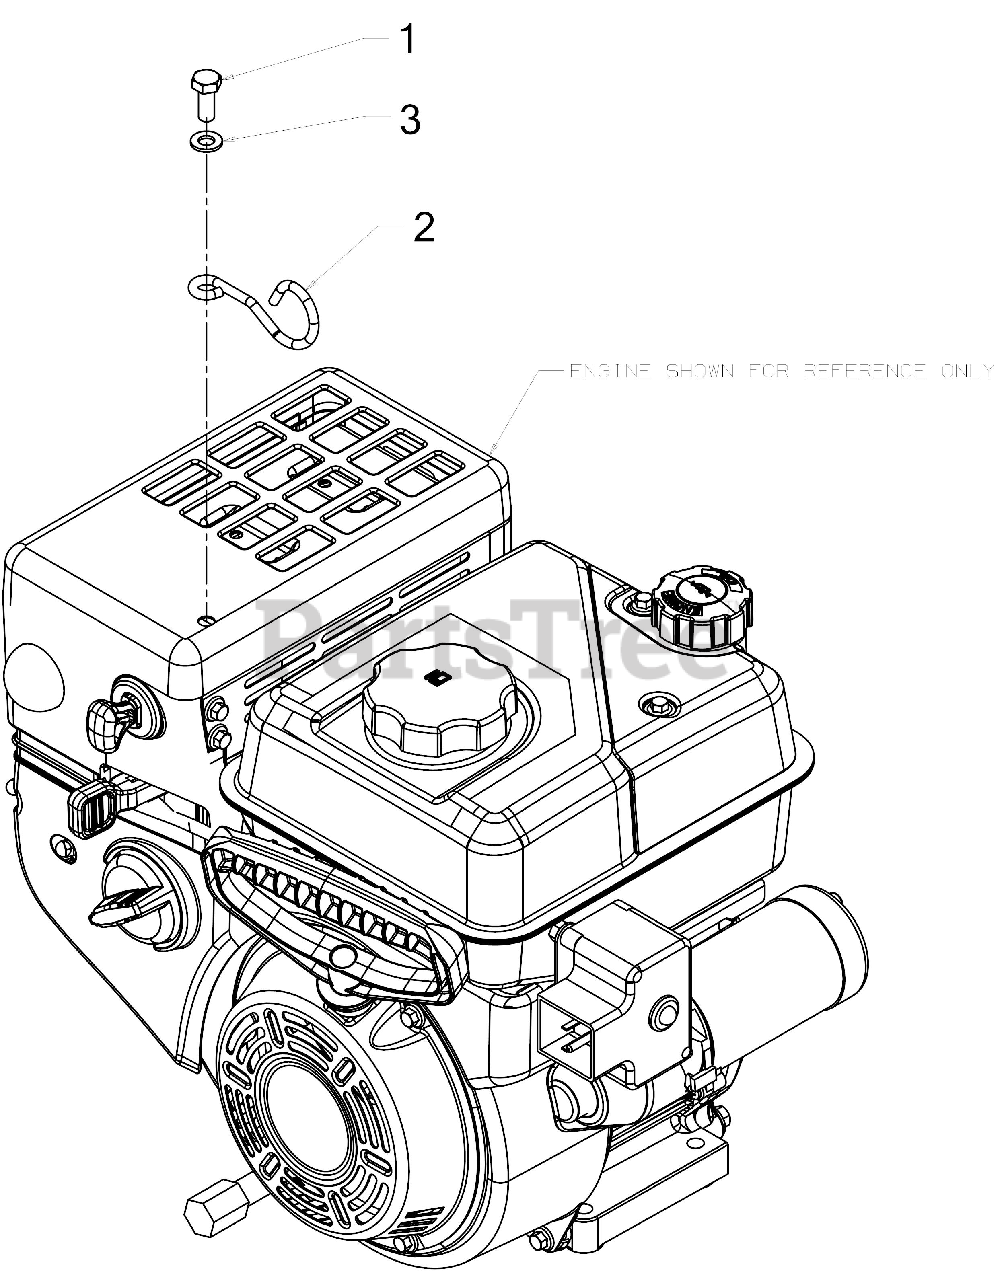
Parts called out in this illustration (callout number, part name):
1	HEX SCREW M8-1.25 x 20 GR8
2	CABLE GUIDE
3	FLAT WASHER
